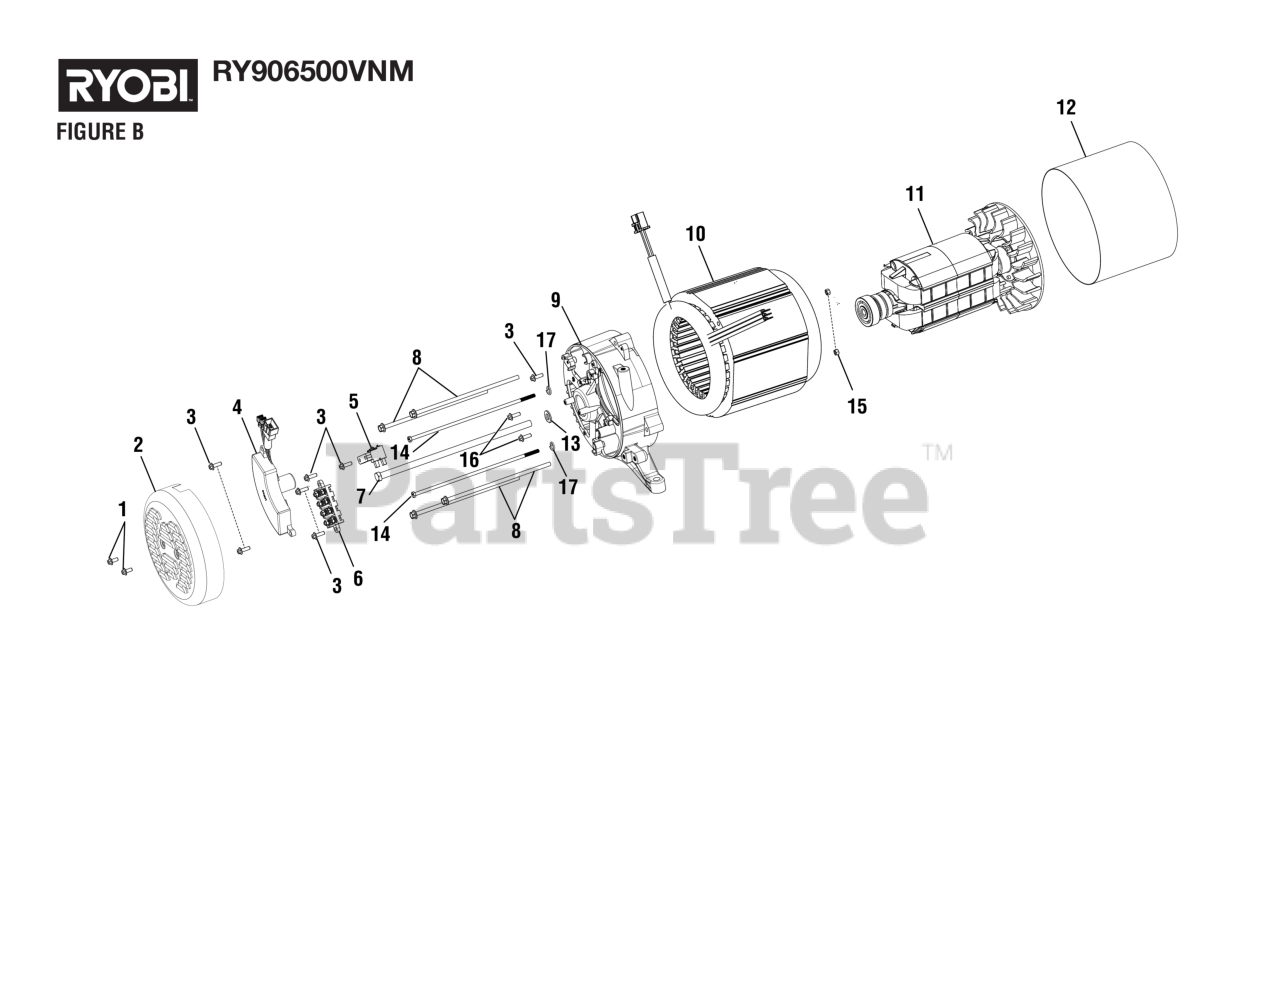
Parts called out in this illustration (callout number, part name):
1	Bolt (M5 x 12 mm, Hex Flange Hd.)
2	Engine Cover
3	Bolt (M5 x 16 mm, Hex Flange Hd.)
4	Automatic Voltage Regulator
5	Brush Assembly Kit
6	Terminal Block Assembly
7	Rotor Bolt (M10 x 272 mm, Hex Hd.)
8	Bolt (M6 x 187 mm, Flange Hex Hd.)
9	Bearing Support
11	Rotor Assembly
12	Stator Band (139 mm)
13	Rotor Washer
14	Bolt (M6 x 224 mm, Hex Hd.)
15	Hex Nut (M5)
16	Bolt (M5 x 10 mm, Flange Hex Hd.)
17	Lock Washer (M5)
